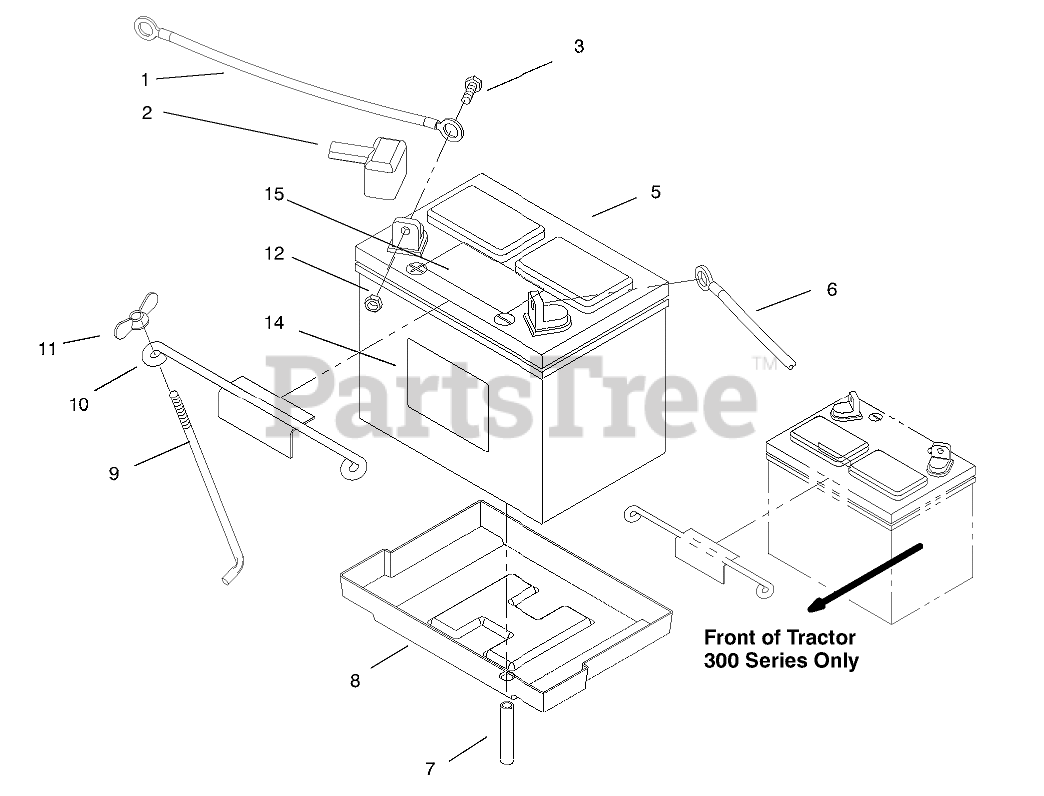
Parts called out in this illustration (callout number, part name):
1	CABLE-BLACK
2	BOOT-TERMINAL
3	SCREW-HH
5	Battery
6	ASSY WIRE
7	TUBE-21" BATTERY DRAIN
8	TRAY-BATTERY
9	HOOK-BATTERY RETAIN
10	HOLDDOWN-BATTERY
11	NUT-WING
12	NUT-LOCK, NI
